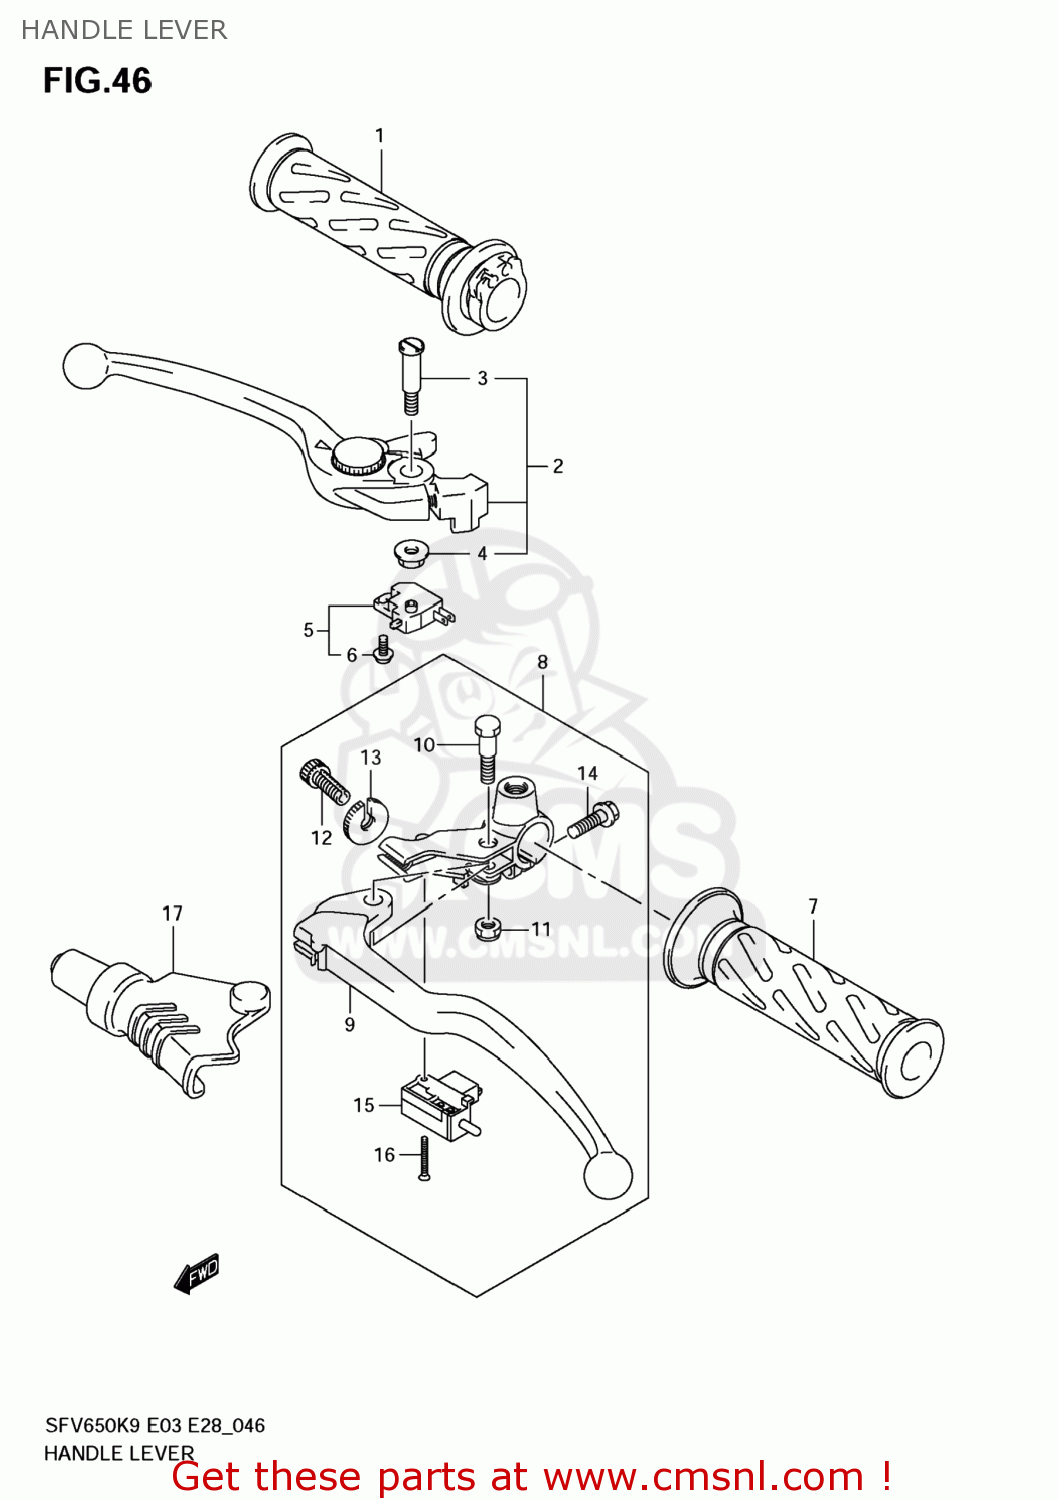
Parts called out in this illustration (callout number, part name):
1	GRIP,THROTTLE
2	LEVER ASSY,BRA
3	BOLT,PIVOT
4	NUT
5	SWITCH ASSY,ST
6	SCREW
7	GRIP,L
8	LEVER ASSY,CLUTCH
9	LEVER,CLUTCH
10	BOLT,LEVER PIVOT
11	NUT
12	ADJUSTER,WIRE
13	NUT,LOCK
14	BOLT
15	SWITCH,CLUTCH
16	SCREW
17	COVER,CLUTCH LEVER
